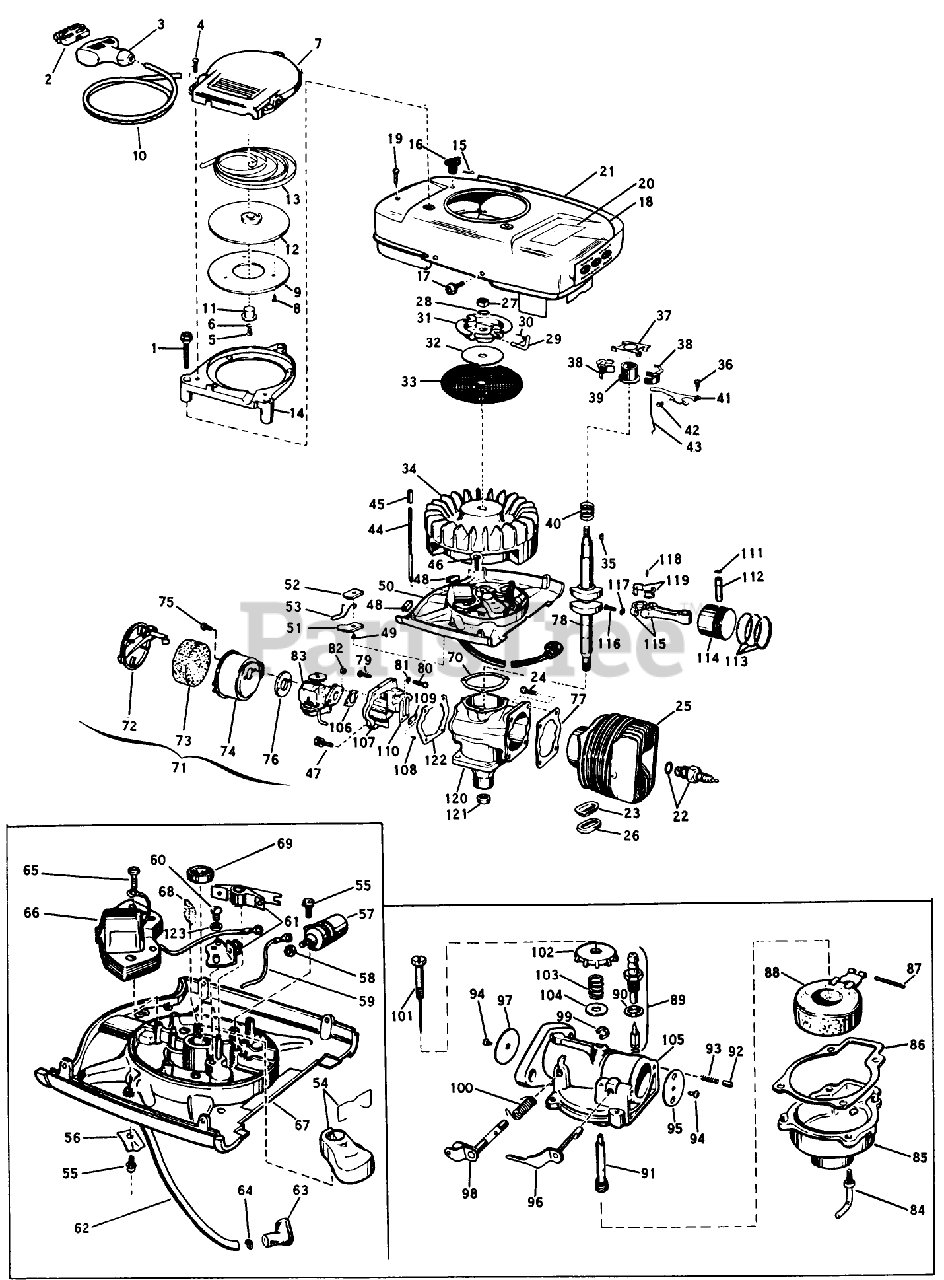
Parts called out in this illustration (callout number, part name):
9	Plate-Pulley
13	RECOIL SPRING
15	Cotter Pin-Choke Knob
16	KNOB, CHOKE BAR
17	SCREW S
22	Spark Plug
26	GASKET S
29	PIN - STARTER
39	COLLAR S
41	GOVERNER LEVER AY
42	WEAR BLOCK S
43	GOVERNOR ROD S
47	SCREW S
49	Screw Shut-off Switch
61	BREAKER AY. S
63	Cover-Rubber
70	GASKET S
73	AIR FIL.ELEM S
75	SCREW S
77	GASKET S
79	SCREW S
82	STOP NUT
94	Screw-Choke Disc
96	CHOKE SHAFT&LVR AY
101	NEEDLE AY. S
103	Spring-Ndl. Adj.
106	GASKET S
109	PLATE-BACKUP, REED
111	RING-RETAINING
119	LINER ASM
